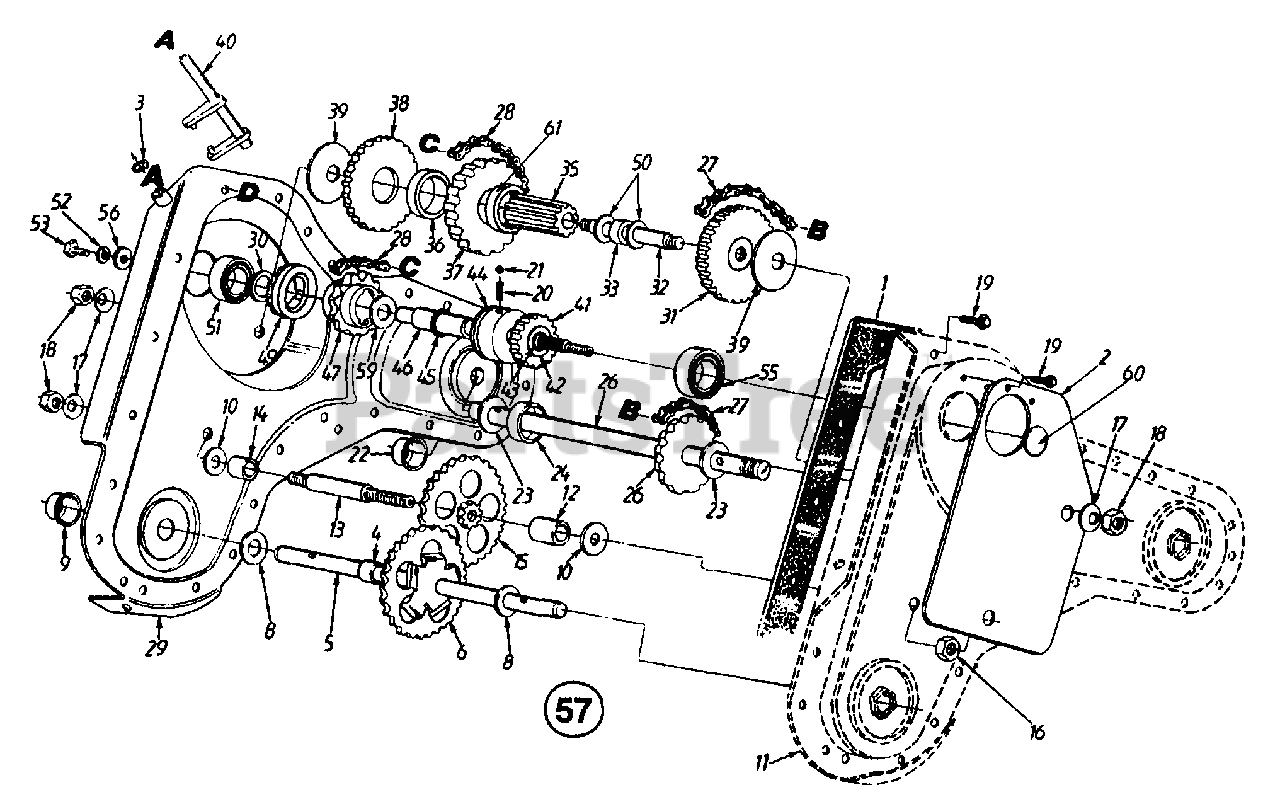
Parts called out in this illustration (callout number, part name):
1	Chain Case Gasket
3	Snap Ring
4	Spacer .735" I.D. x .886" O.D.
5	Wheel Shaft
6	Spur Gear 46T
8	Fl-Wash. .76" I.D. x 1.5" O.D.
9	Shaft Seal
10	Thr. Wash. .445 I.D. x 1.92 O.D. x .060
13	Jack Shaft 2.06" Lg.
14	Spacer .635" I.D. x 1" O.D. x .37" Thk.
15	Gear Idler Ass'y.
16	Hex Patch L-Nut 7/16-20 Thd.
17	Bell-Wash. .45" I.D. x 1" O.D.
18	Hex Nut 7/16-20 Thd.
19	Hex Wash. Hd. TT-Tap Scr. 1/4-20 x .5" Lg.
20	Spring Detent
21	Ball Detent
22	Shaft Seal
23	Thrust Wash. 1.03" I.D. x 1.62"
24	Spacer 1" I.D. x 2" O.D. x .5" Thk.
26	Tine Shaft Ass'y.
27	Chain #50 5/8" Pitch x 52 Links - Endless
28	Chain - #41 1/2" Pitch x 30 Links - Endless
30	Fl-Wash .7/16" I.D. x 1-3/8" O.D.
31	Gear and Sprocket Ass'y.
32	Jack Shaft 5" Lg.
33	Spacer.636" I.D. x .86" O.D.
35	Spur Gear 10T
36	Spacer 1.5" I.D. x 1.76" O.D.
37	Sprocket - #41 Chain
38	Reverse Gear 467
39	Thrust Wash. .445" I.D. x 1.92"
40	Shifter Ass'y.
41	Spur Gear 17T
42	Fl-Wash. .69" I.D. x 1.06" O.D.
43	Wire Ring
44	Clutch Collar
45	Retaining Ring .875" Shaft
46	Drive Shaft
47	Sprocket 11T
49	Spur Gear 167
50	Fl-Wash. 5/8" I.D. x 1" O.D.
51	Ball Bearing .669" I.D.
52	L-Wash. 1/4" I.D.
53	Hex Bolt 1/4-20 x .62" Lg.
55	Ball Bearing
56	Fl-Wash. .281" I.D. x .875" O.D.
57	Gear Case Ass'y. Comp.
59	Fl-Wash. .88" I.D. x 1.5" O.D.
60	Button Plug
61	Spacer 1.52" I.D.
